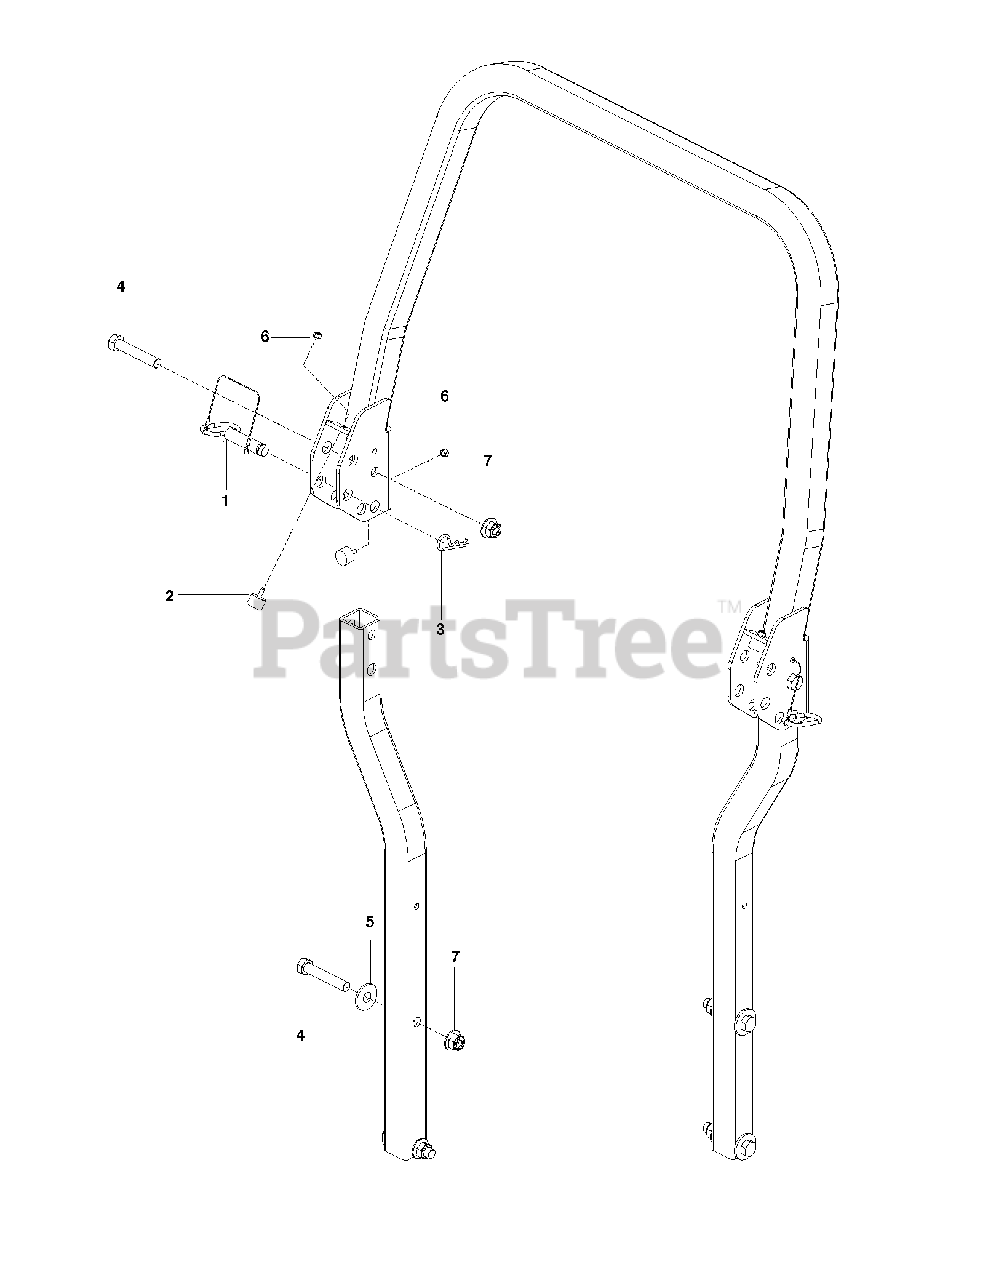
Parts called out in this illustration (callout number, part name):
2	BUMPER, MALE STUD, 1/4-20
3	PIN HAIR .148 X 2-15/16 #210
4	5/8-11 X 3-1/2 HHB GRADE 5
5	WASHER, 5/8 FLAT
6	RP_NUT 1/4-20 NYLOC
7	NUT 5/8-11 FLG NYLOC ZD
